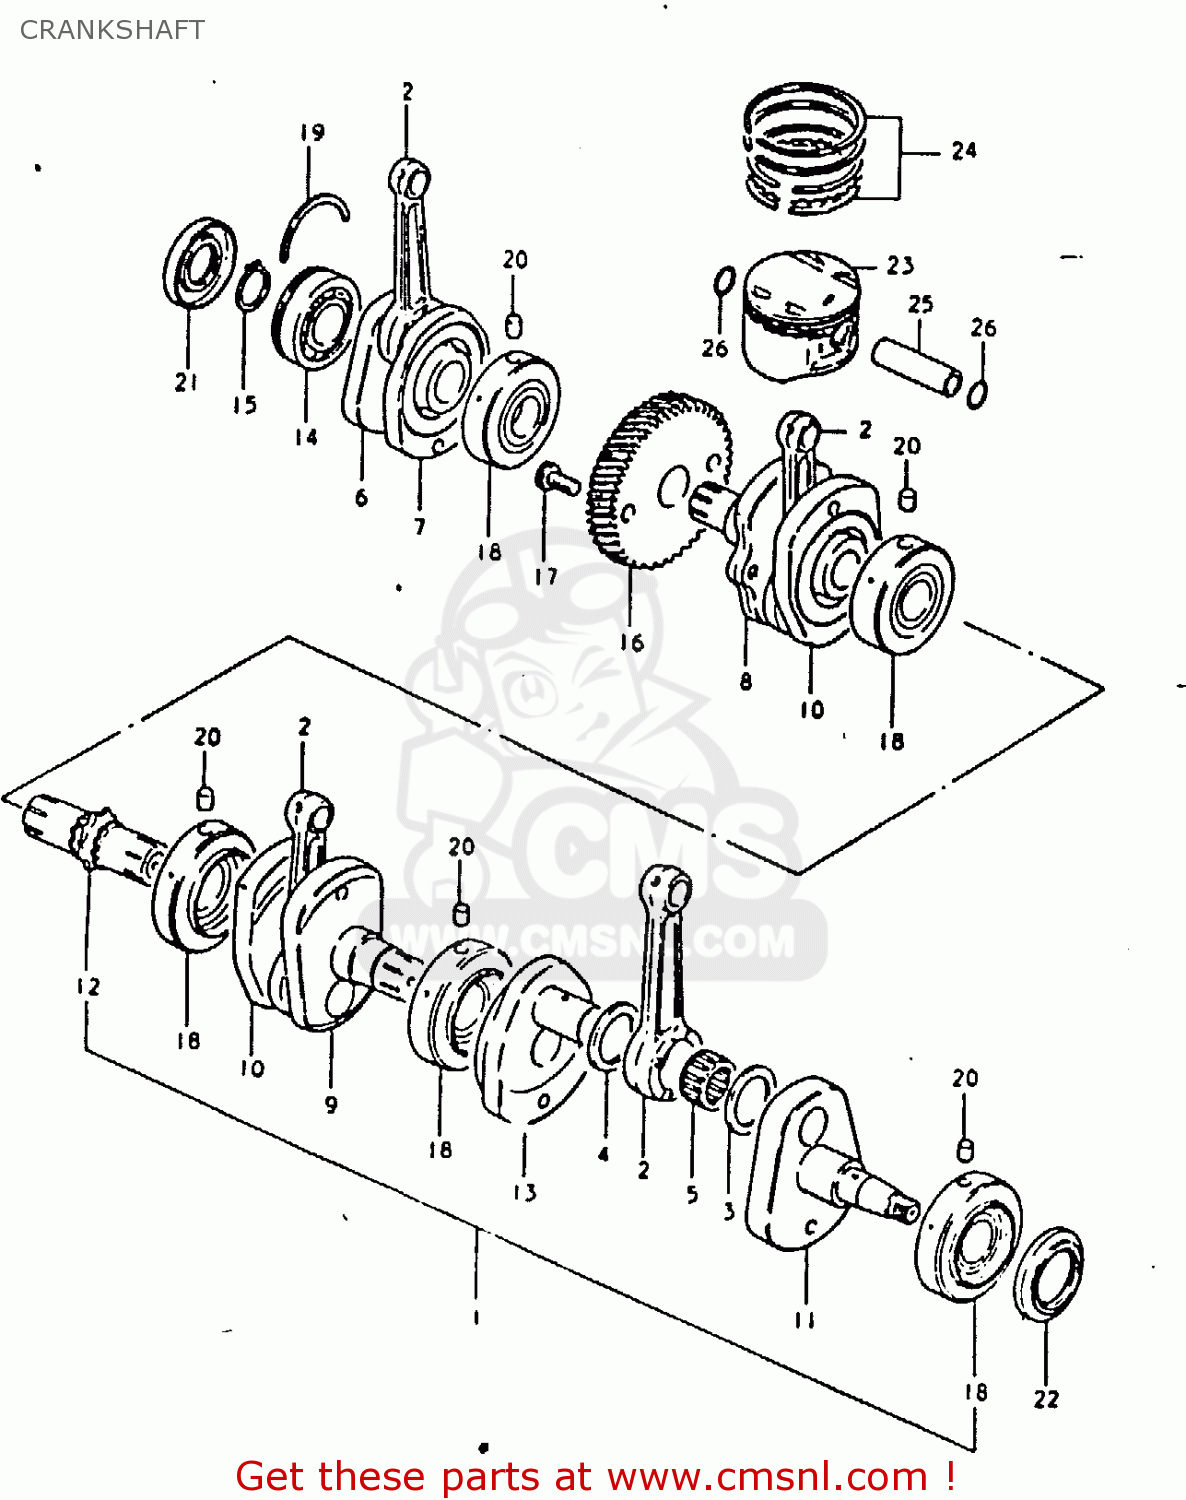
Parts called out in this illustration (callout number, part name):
1	CRANKSHAFT ASSEMBLY
2	CONNECTING ROD
3	WASHER(31X48.5X1)
4	WASHER(31X48.5X2)
5	BEARING(31X39X21)
6	CRANKSHAFT,RIGHT
7	WEB,CRANK
8	CRANKSHAFT
9	CRANKSHAFT,MIDDLE,LEFT
10	WEB,CRANK,MIDDLE
11	CRANKSHAFT,LEFT
12	SHAFT,TIMING CHAIN DRIVE
13	WEB,CRANK,LEFT
14	BEARING(30X72X19)
15	CIRCLIP,30MM
16	GEAR,PRIMARY DRIVE
17	BOLT
18	BEARING
19	C RING
20	PIN
21	SEAL,OIL(30X72X11)
22	SEAL,OIL(47.3X60X6.5)
23	PISTON
24	RING SET,PISTON
25	PIN,PISTON
26	CIRCLIP,PISTON PIN
